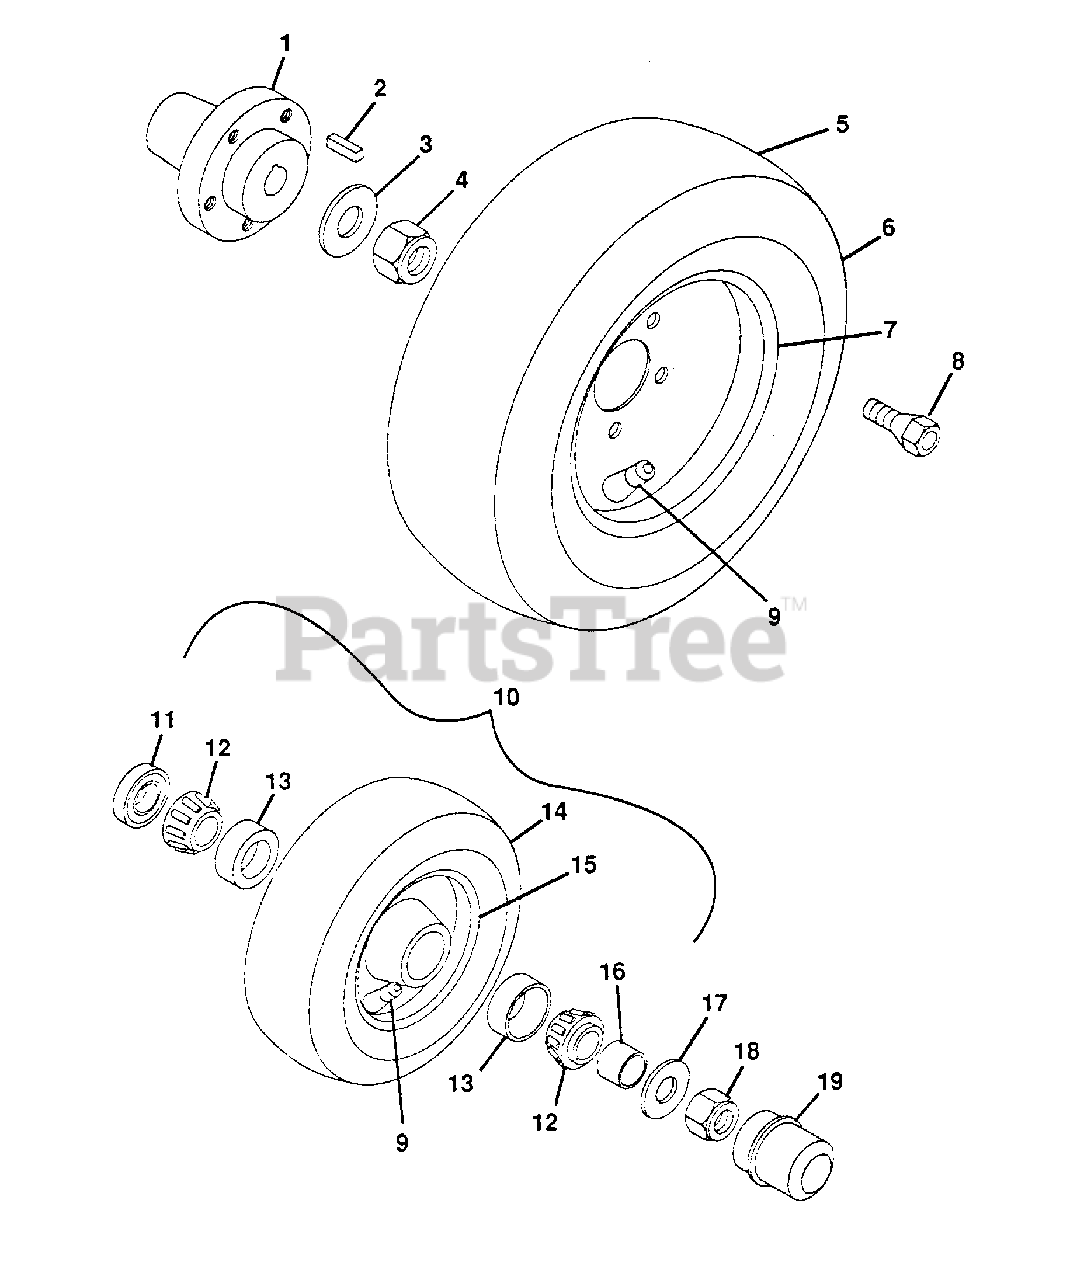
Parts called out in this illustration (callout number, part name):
1	Hub, Wheel
2	Key, Square .312x2.25
3	Washer, Flat 1.062x2.000x.134
4	Nut, Lock 1-14
5	Tire, Assembly 23x10.50-12
6	Tire, Rear 23x10.50-12
7	Rim, Weldment
8	Bolt, Hub 7/16-20x.75 Special
9	Assembly, Valve Stem
10	Tire, Assembly 16-7.50-8
11	Seal, Oil
12	Bearing, Cone LM 11949
13	Bearing, Cup LM 11910
14	Tire, Front 16x7.50-8
15	Rim, Front Wheel Assembly
16	Spacer
17	Washer, Flat .656x1.312x.095
18	Nut, Lock 5/8-11
19	Cap, Dust
